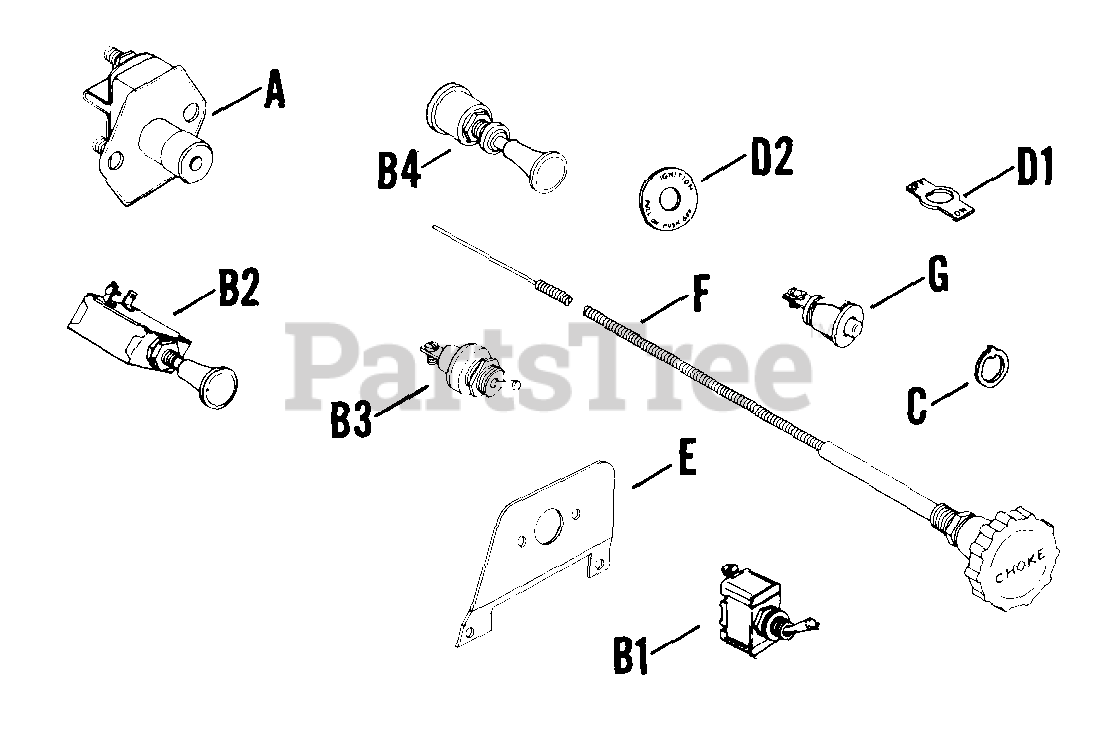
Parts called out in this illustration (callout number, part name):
B3	KIT - USE 223072-S
D1	PLATE - DISCONTINUED
G	SWITCH - DISCONTINUED
